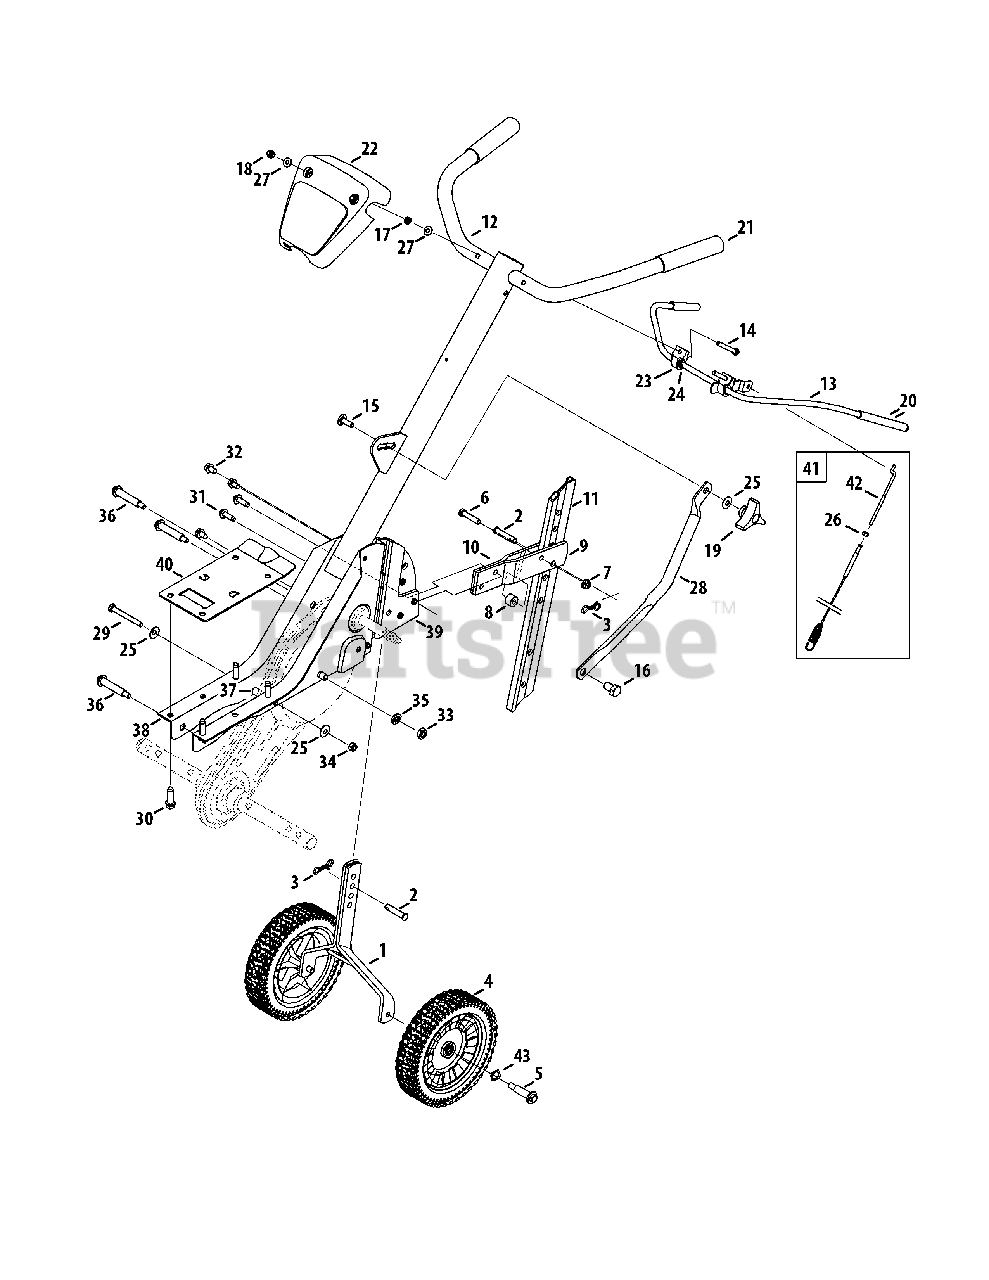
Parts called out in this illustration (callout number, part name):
1	Wheel Bracket Assembly
2	Clevis Pin, .375 x 1.75
3	Cotter Pin
4	Wheel Assembly, 8 x 1.75
5	Shoulder Screw, 3/8-16 x .496 x 1.445
6	Hex Screw, 5/16-18 x 1.50
7	Flange Lock Nut, 5/16-18
8	Spacer, .325 x .75 x .520
9	LH Tail Bracket
10	RH Tail Bracket
11	Depth Bar
12	Handle Assembly
13	Clutch Bail
14	Hex Screw, 1/4-20 x 2.25
15	Carriage Screw, 5/16-18 x 1.00
16	Hex Screw, 1/2-20 x .750
17	Jam Nut, 1/4-20
18	Lock Nut, 1/4-20
19	Handle Knob
20	Grip, Clutch Bail
21	Grip, Handle
22	Handle Cover
23	Clutch Bail Holder
24	Flat Washer, .406 x .875 x .059
25	Bell Washer, .340 x .872 x .060
26	Jam Nut
27	Flat Washer, .271 x .630 x .065
28	Handle Brace
29	Hex Screw, 5/16-18 x 3.00
30	SEMS Screw, 3/8-16
31	Self-Tapping Screw, 5/16-18 x 1.00
32	Hex Washer Screw, 5/16-18 x .750
33	Jam Nut, 7/16-20
34	Flange Lock Nut, 5/16-18
35	Lock Washer, 7/16
36	Shoulder Screw, 5/16-18 x .475 x 2.11
37	Spacer, .47 x .96
40	Engine Mounting Plate
41	Forward Clutch Cable
42	Z-Fitting (inc. #43)
43	Wave Washer .531 x .781 x .013
